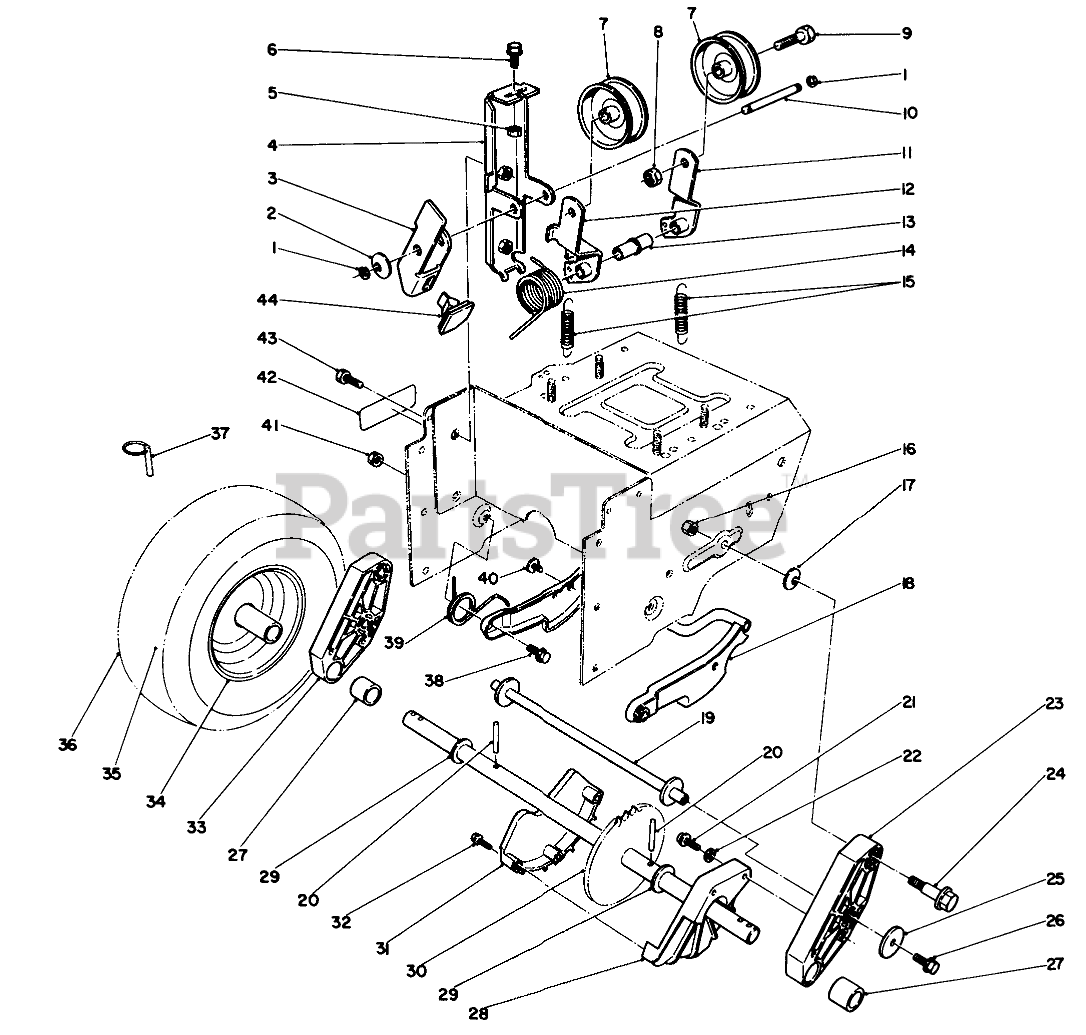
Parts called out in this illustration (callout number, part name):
1	RING-RETAINING
2	WASHER-CURVED
3	ARM-BRAKE
4	IDLER ARM BRACKET ASM
5	NUT-LOCK, NI
6	SCREW-HHF
7	PULLEY-IDLER
8	NUT-LOCK, NI
9	SCREW-HH
10	PIN-IDLER
11	ARM-IDLER, TRACTION
12	ARM-IDLER, IMPELLER
13	BUSHING-IDLER
14	TORSION SPRING
15	SPRING-EXTENSION
16	NUT-LOCK, NI
17	WASHER-SPRING
18	Latch-Arm
19	PIVOT TUBE WA
20	PIN-ROLL, SLOTTED
21	SCREW-HWH
22	WASHER-FLAT
23	Pivot Arm Assembly L.H. (Incl. Ref. #27)
24	BOLT-SHOULDER
25	WASHER
26	SCREW-TAPTITE
27	BUSHING-AXLE
28	GUARD-CHAIN, LH
29	WASHER-THRUST
31	GUARD-CHAIN, RH
32	SCREW-PPH
33	Pivot Arm Assembly R.H. (Incl. Ref. #27)
34	WHEEL RIM
35	INNER TUBE
37	PIN-LYNCH
38	SCREW-SHOULDER
39	SPRING-LATCH, TORSION
40	FASTENER-PANEL
41	NUT-LOCK, NI
42	Decal-Warning
43	SCREW-HHF
44	Brake Pad
